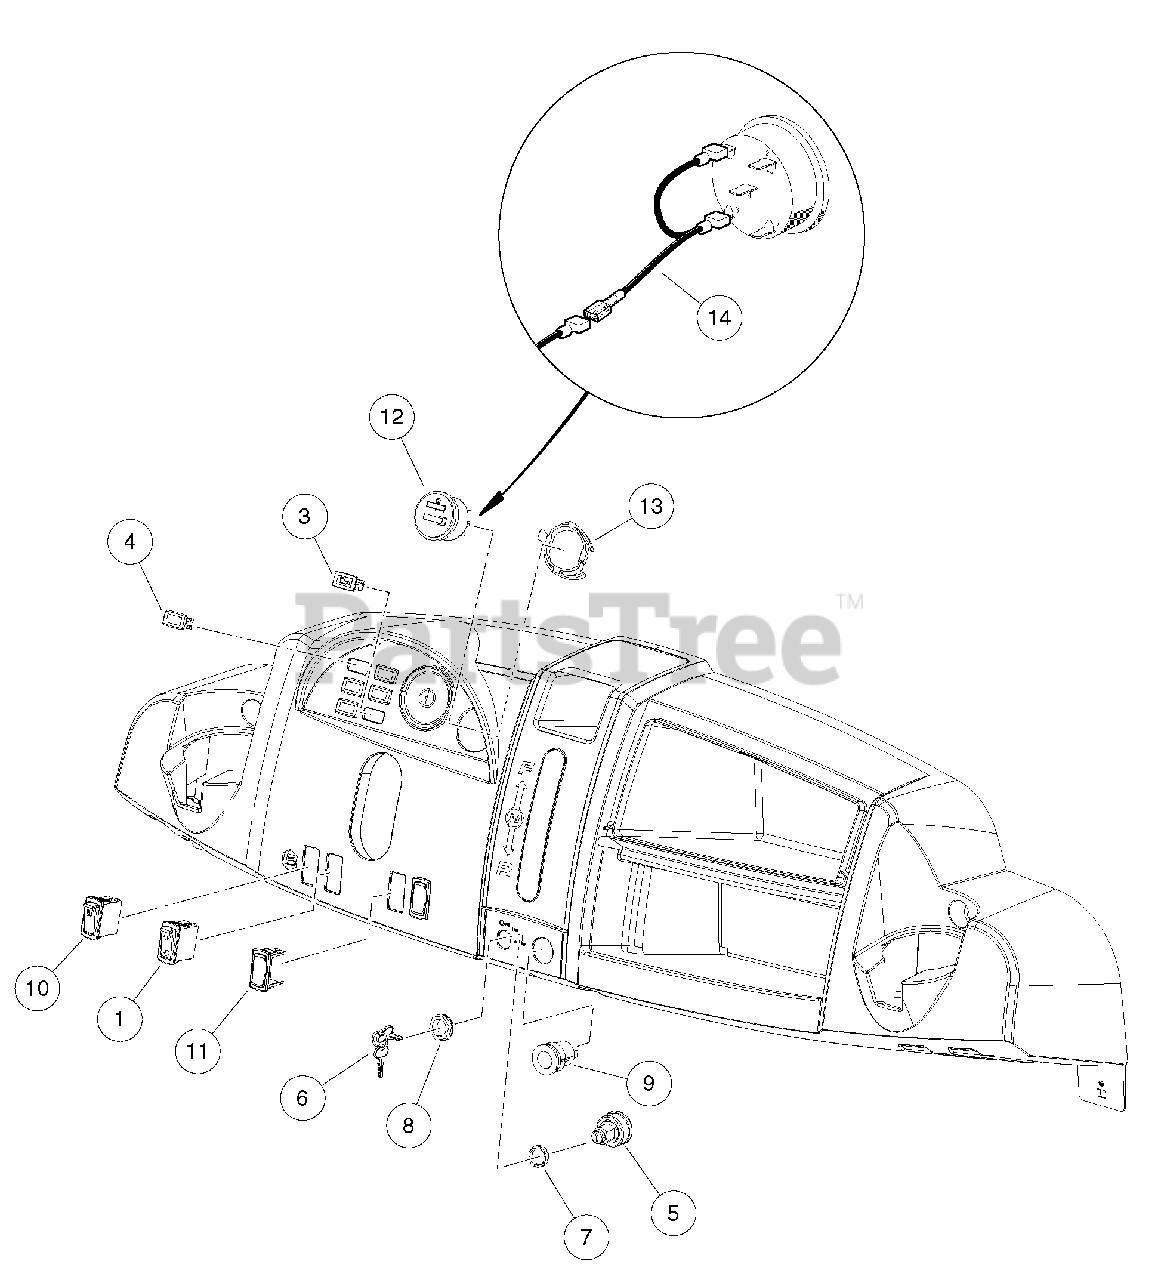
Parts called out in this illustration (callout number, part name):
1	Switch, Rocker, Spring Return, Bed Lift
2	Instl, Elec Sys Awd Gas Fh680d
3	Light, Oil
4	Plug, Hole
5	Key Switch 12v Key Start
7	Spacer, Keyswitch
8	Nut, Key Switch
9	Receptacle, Accessory
10	Switch, Rocker, Light
11	Cover, Hole, Switch, Rocker
12	Gauge Fuel-hour Sep Gnd
13	Clip, Meter, Round
14	Asm Wire Meter F-h Jumper
